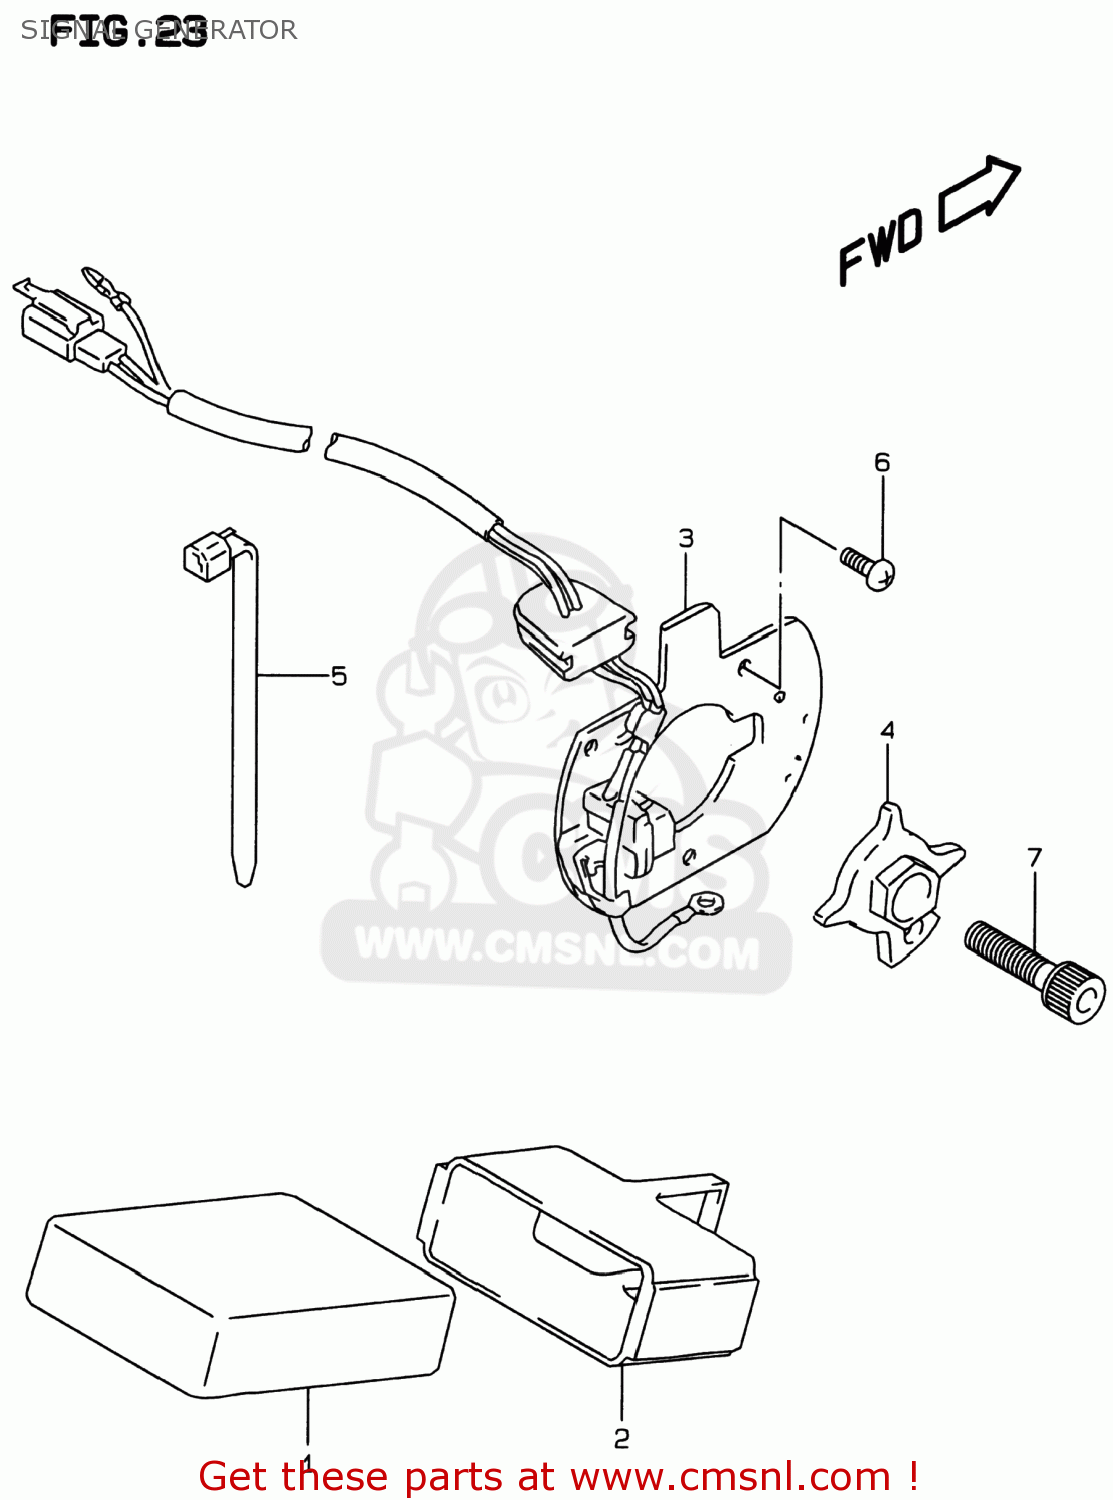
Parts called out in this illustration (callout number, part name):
1	IGNITOR ASSY
2	CUSHION,IGNITOR
3	GENERATOR ASSY,SIGNAL
4	ROTOR,SIGNAL GENERATOR
5	CLAMP(L:95)
6	SCREW
7	BOLT
